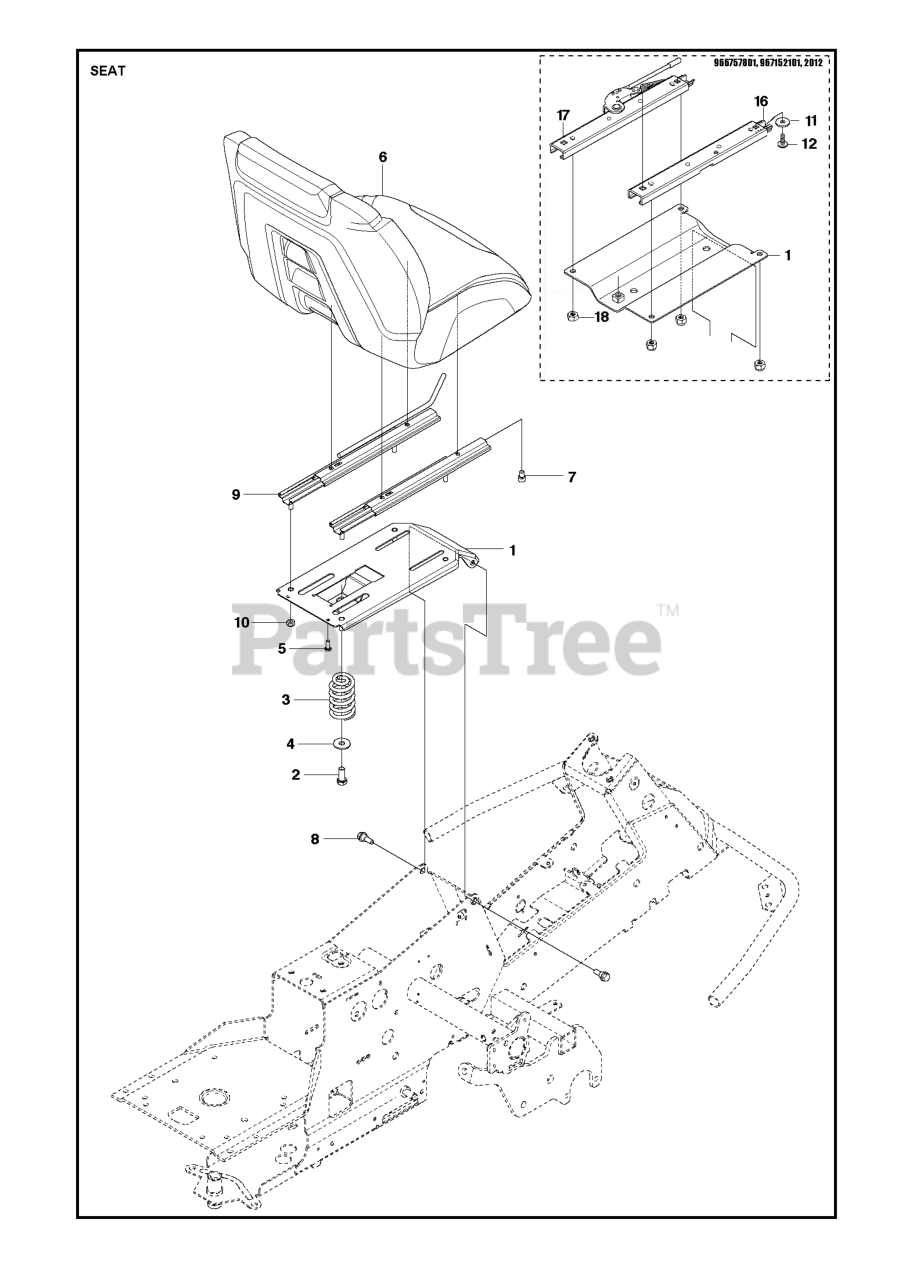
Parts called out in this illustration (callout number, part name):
1	SEAT BRACKET 300 ASSY GREY
1	SEAT BRACKET
2	Screw M10x25
3	SEAT SPRING
5	SCREW
6	SEAT HUSQVARNA HIGH BACK
6	SEAT ASSY KIT HIGH HVA
7	SCREW IHSCM
9	SEAT ADJUSTER LEFT & RIGHT
10	LOCKNUT M8
11	WASHER
12	BOLT.FIN.HEX.5/16-18X3/4
16	RAIL
17	RAIL
18	LOCKNUT M8
